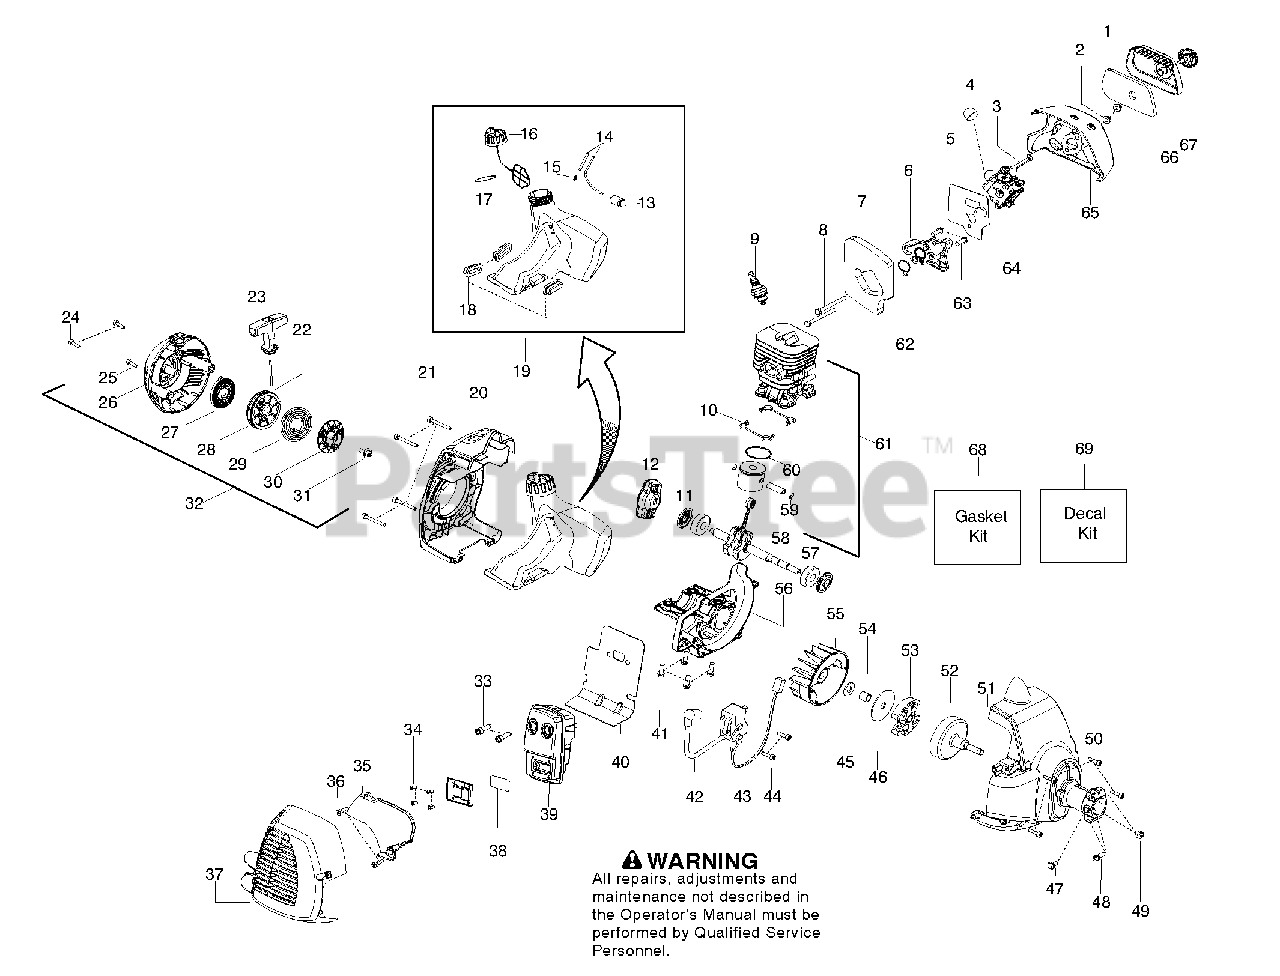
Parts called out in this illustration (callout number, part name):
2	Nut-Carb. Screw
3	Lever - Choke
4	Bulb-Purge
5	Kit-Carb. Gasket
6	Adaptor-Carb.
7	Foam-Gasket (kit)
9	Plug-Spark (RCJ-8Y)
10	Seal-Cylinder (kit)
11	Seal-Crankshaft (kit)
12	Assy-Starter Pawl
13	Assy-Fuel Filter
14	Kit-Fuel Line
15	Fitting-Fuel Line
16	Assy-Cap w/ret.
17	O-ring-Fuel Cap (kit)
18	Isolator-Fuel Tank
19	Kit-Fuel Tank Assy.
20	Shroud - Rear (KIT)
22	Kit-Rope
23	Handle-Starter
26	Starter Hsg. (KIT)
27	Kit-Spring
28	Kit-Starter Pulley
29	Spring - Driver
30	Pulley-Driver
32	Assy-Starter Hsg.
33	Bolt-Muffler
34	Screw
35	Shield-Heat
37	Kit - Muffler Guard
38	Kit-Spark Arrestor
39	Kit-Muffler
40	Gasket-Paper met.(kit)
43	Assy-Leadwire
46	Washer-Clutch
47	Screw
48	Screw
51	Assy-Fan Housing
52	Assy-Clutch Drum
53	Assy - Clutch
56	Crankcase
58	Assy-Crankshaft
59	Retainer-Piston Pin
60	Ring-Piston
61	Kit-Piston/Cyl.
62	Kit-Gasket (adaptor seal)
64	Kit-Carb.
65	Airbox
66	Cover-Air Box
68	Kit-Gasket
69	Kit - Decal
